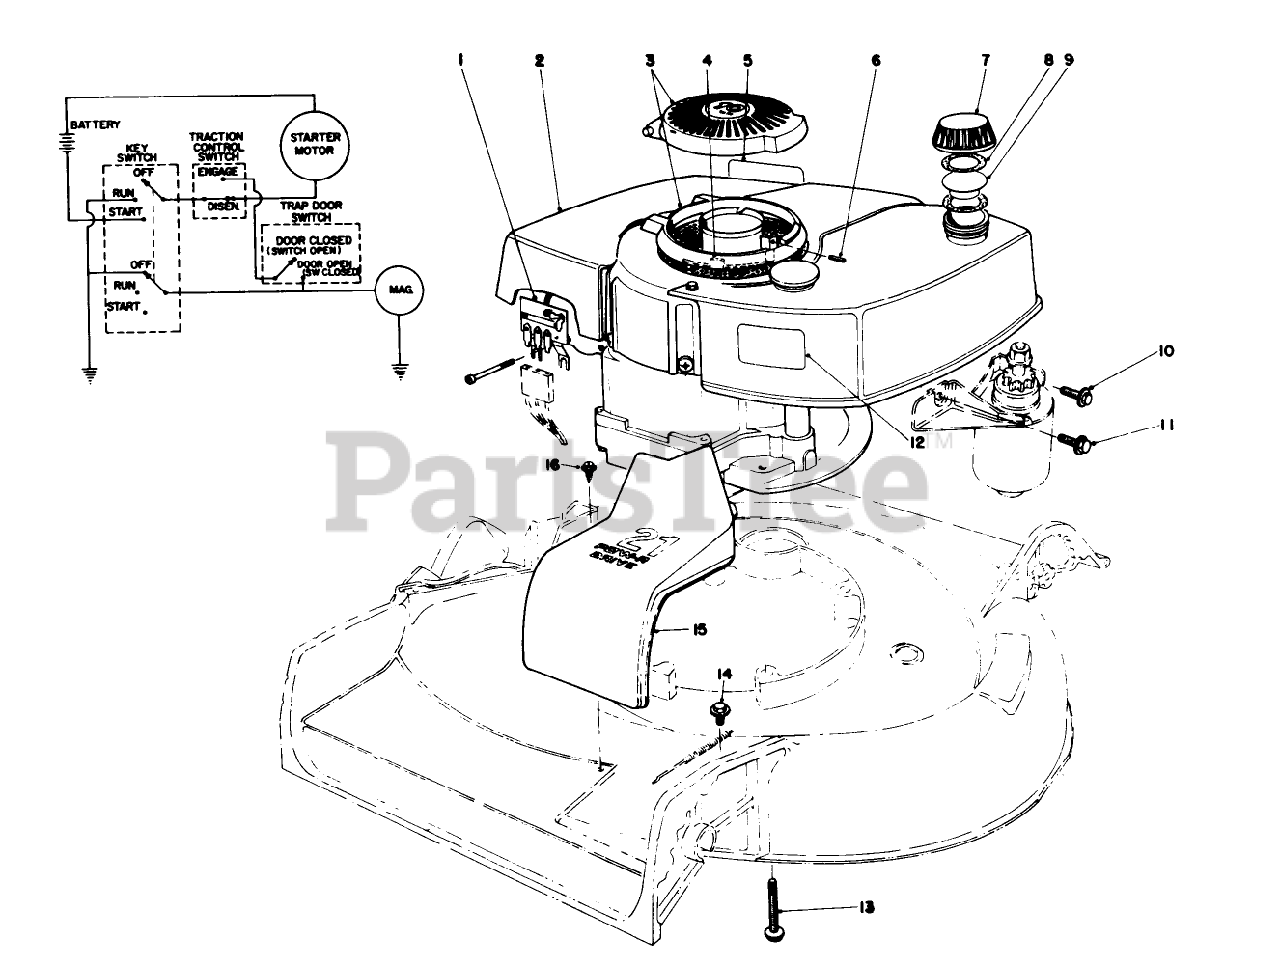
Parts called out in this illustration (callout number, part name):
2	Engine
6	SPRING PIN
8	GASKET
10	SCREW
12	Decal Engine
13	3/8-16 X 2-3/4 CAPSCR
14	SCREW-THD ROLL, HWH
15	BELT DRIVE COVER
16	SCREW
